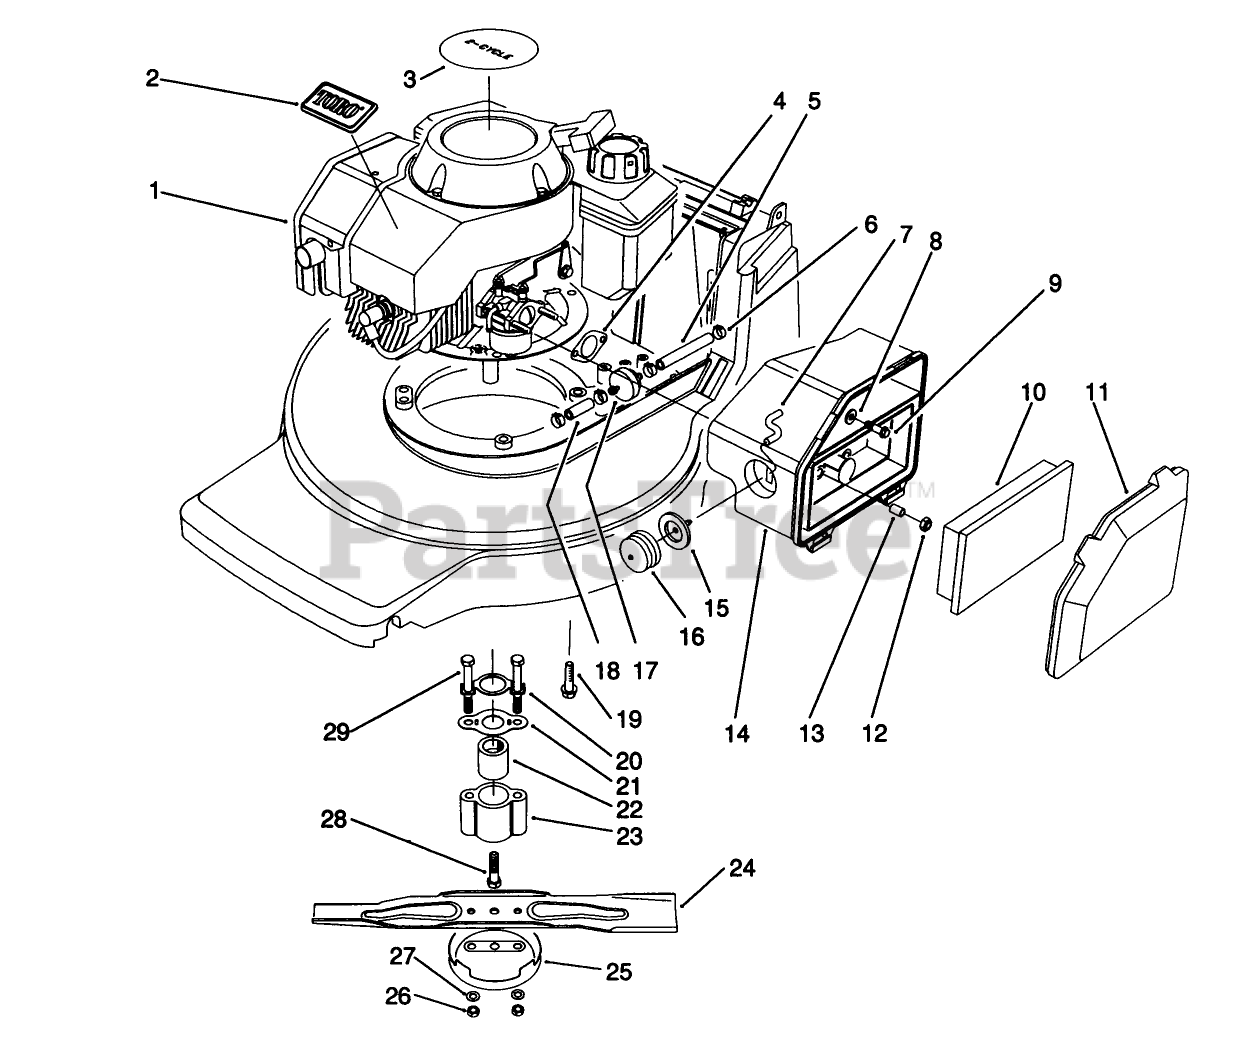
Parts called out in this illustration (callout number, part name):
1	ENGINE 121CC INT'L 2CYC
2	TORO LOGO PLT
3	DECAL- 2 CYC RECOIL
4	GASKET-AIR CLEANER
5	HOSE-FUEL
6	CLAMP-FUEL LINE
7	HOSE-PRIMER
8	WASHER-FLAT
9	SCREW-HH
10	ELEMENT-AIR CLEANER
11	COVER-AIR CLEANER
13	SPACER
14	BODY-AIR CLEANER
15	BODY-PRIMER
16	BULB-PRIMER
17	FILTER-FUEL
18	HOSE-FUEL
19	Bolt-Engine
20	BLADE RETAINER BRKT
21	SPRING FRICTION
23	RETAINER
24	Blade-48cm
25	CUP-SCALP, ANTI
26	NUT-LOCK
27	WASHER
28	SCREW - CRANKSHAFT
29	SCREW - BLADE
